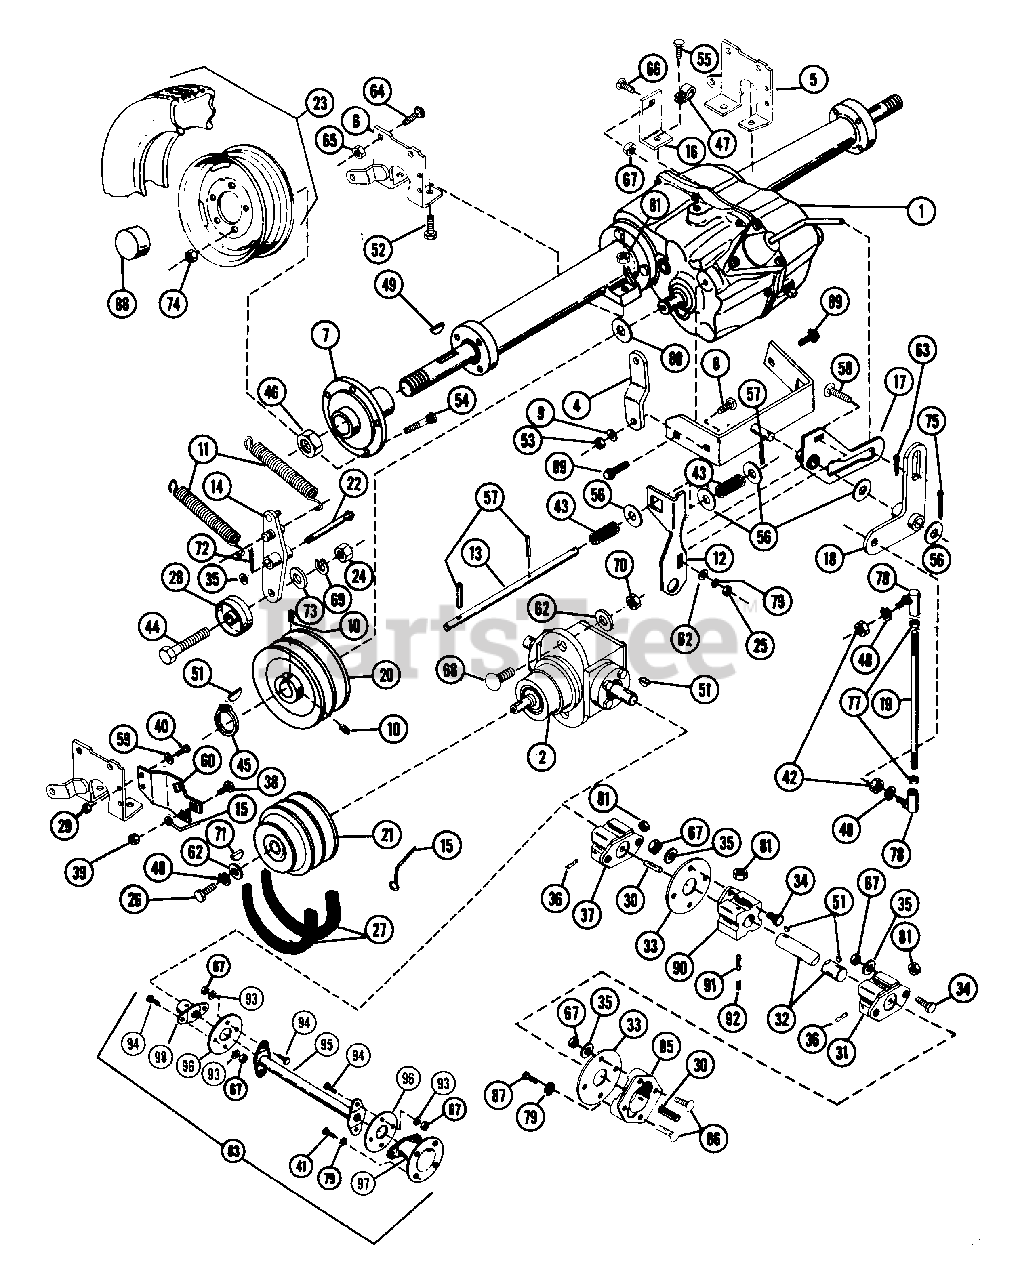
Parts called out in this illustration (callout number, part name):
1	TRANSAXLE
2	T-DRIVE HEAD ASSEMBLY
3	BRACKET
5	LH AXLE SUPPORT
6	RH AXLE SUPPORT
7	WHEEL HUB ASSEMBLY
8	BLT-RDHDSQNK .38-16X1.0 GR5PL
9	WSHR-FL-STL.406X.812X.065PL
10	SCR-SET .32-18X.50 SKH
11	SG-TENS .121X1.00X6.5 WLD 12
12	BELLCRANK ARM
14	IDLER ARM
15	BELT FINGER
16	BRACKET
17	BELLCRANK
18	BELLCRANK
22	IDLER PIN
23	10.50 X 23 REAR TIRE ASSY.
23	TIRE
23	WHL
23	8.50 X 23 REAR TIRE ASSY.
23	WHL 12X8.50
24	NUT-HEX .375-16
25	NUT-JAM .375-16 PL
26	BLT-HEX .31-18X.75 PL GR5
27	V-BELT, 5L-RAW EDGE (SET)
28	IDLER-FLAT 3.218X.38
29	NUT-LK-CTR .250-20 PL
30	PIN-GRV .313X.75 TP D
31	DRIVE HUB
32	DRIVE SHAFT - GEAR
33	SPACER COUPLING
34	BLT-HEX .31-18X.75 PL GR2
35	WSHR-FL-STL.344X.688X.065PL
36	LOCK STUD
37	DRIVE HUB
38	BLT-RDHDSQNK .38-16X.75 SHT PL
39	NUT-LK-FLG .375-16 GR A PL
40	BLT-HEX .25-20X.75 PL GR2
41	BLT-HEX .38-16X.63 PL GR2
42	NUT-LK .312-24
43	SG-COMP .072X.687X.75
44	BLT-HEX .38-16X2.00 PL GR2
45	RG-RTNG-EXT .750X.042
46	NUT-LK-JAM 1.0-14 PL
47	J-CLAMP
48	WSHR-LK .312X.097 PL HVY
49	KEY-WDRF .25X2.125X.531
51	KEY-WDRF .188X.75X.313 SAE 9
52	BLT-HEX .38-16X1.50 PL GR5
53	NUT-LK-CTR .375-16 GR A PL
54	CARRIER LUG BOLT
55	BLT-HEX .38-16X.75 PL GR2
56	WSHR-FL-STL .531X1.062X.095 PL
57	PIN-ROLL .125X1.00
58	BLT-RDHDSQNK .38-16X.75 SHT PL
59	WSHR-FL-STL.312X.734X.065PL
60	MOUNTING BRACKET
62	WSHR-FL-STL .38X.875X.083 PL
63	PIN-COTR .12X.75 PL
64	BLT-RDHDSQNK .50-13X1.25GR5PL
65	NUT-LK-CROWN .50-13 GR C PL
66	BLT-RDHDSQNK .31-18X1.00 PL
67	NUT-LK .312-18 GR A PL
68	BLT-RDHDSQNK .38-16X1.25 PL
69	WSHR-LK .375X.115 HVY PL
70	NUT-LK-CTR .375-16 GR A PL
71	KEY-WDRF .188X.625X.25 SAE 61
72	PIN-COTR .12X1.0 PL
73	WSHR-FL-STL .438X1.0X.083 PL
74	NUT-LUG .437-20 YWZC
75	PIN-COTR .15 X 1.0 PL
77	NUT-JAM .312-18 PL
78	BALL JOINT
79	WSHR-LK .375X.094 MED PL
80	WSHR-FL-STL .781X2.000X.059
81	NUT-LK TOP .375-16 GR C YWZC
83	DRIVE SHAFT ASSY GEAR
85	DRIVE HUB - FLYWHEEL SINGLE
86	BLT-SERRDHD SL .31-18X.87 PL
87	@BLT-HEX .38-16X.88 PL GR2
88	REAR HUB CAP
89	BLT-SCRHFWH .38-16X.75 PL
90	DRIVE HUB
90	DRIVE HUB - TWIN SHAFT
91	LOCK STUD
92	SCR-SET .38-16X.50 SKHCUP OH
93	WSHR-FL-STL .38X.875X.083 PL
94	BLT-HEX .31-18X.75 PL GR2
95	DRIVE SHAFT ASSY
96	SPACER COUPLING
97	DRIVE COUPLING
98	COUPLING
